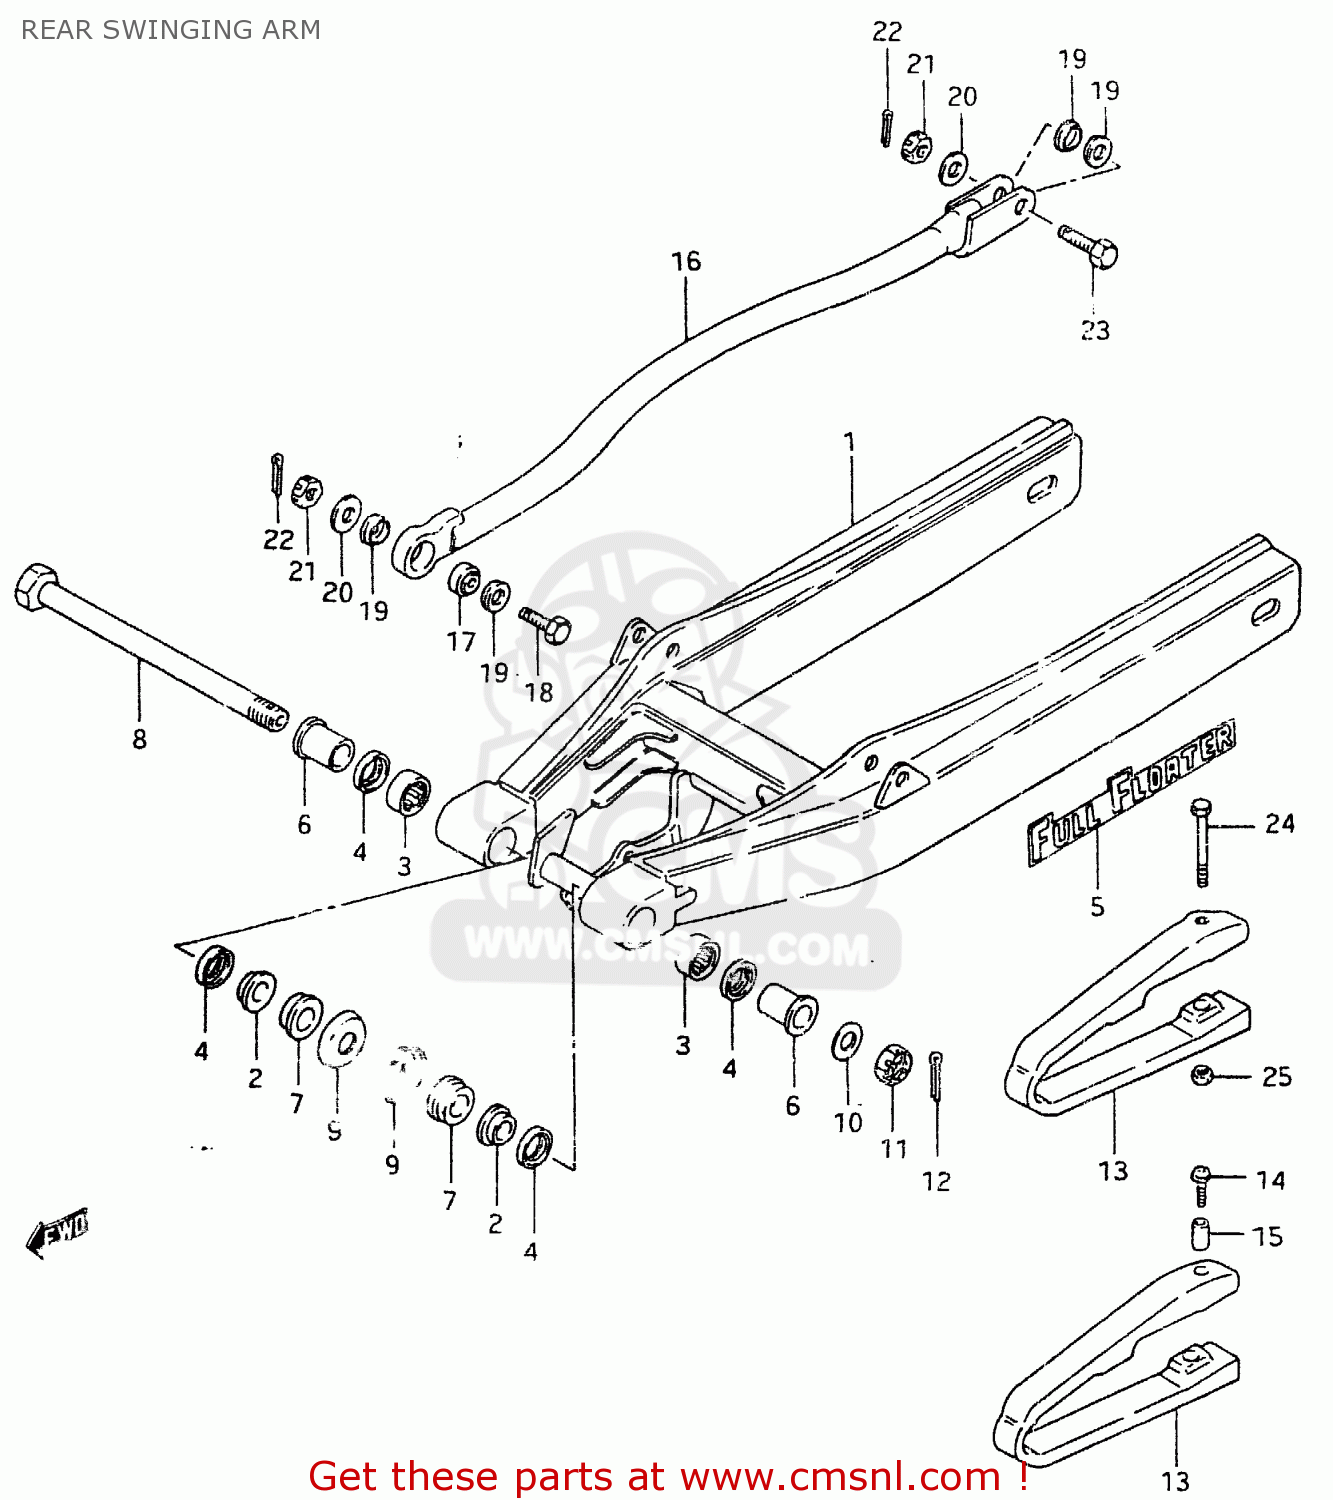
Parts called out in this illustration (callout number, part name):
1	SWING ARM ASSEMBLY,REAR
2	BUSH,RR SWINGINGARM PIVOT
3	BEARING(20X27X20)
4	OIL SEAL
5	EMBLEM,SWING ARM
6	SPACER,RR SWGARM PIVOT
7	SPACER,RR SWGARM PIVOT INNER
8	SHAFT,RR SWINGINGARM PIVOT
9	COVER,RR SWGARM DUST SEAL
10	WASHER
11	NUT 14MM
12	COTTER PIN
13	BUFFER,CHAIN TOUCH DEFLECTOR
14	SCREW,CHAIN TOUCH DEFEND
15	SPACER (5.5X8X4)
16	LINK,REAR TORQUE
17	SPHERICAL BRNG,TORQUE LINK
18	BOLT 8X28
19	20
20	WASHER
21	NUT 8MM
22	PIN 20X20
23	BOLT 8X29.5
24	BOLT
25	NUT
